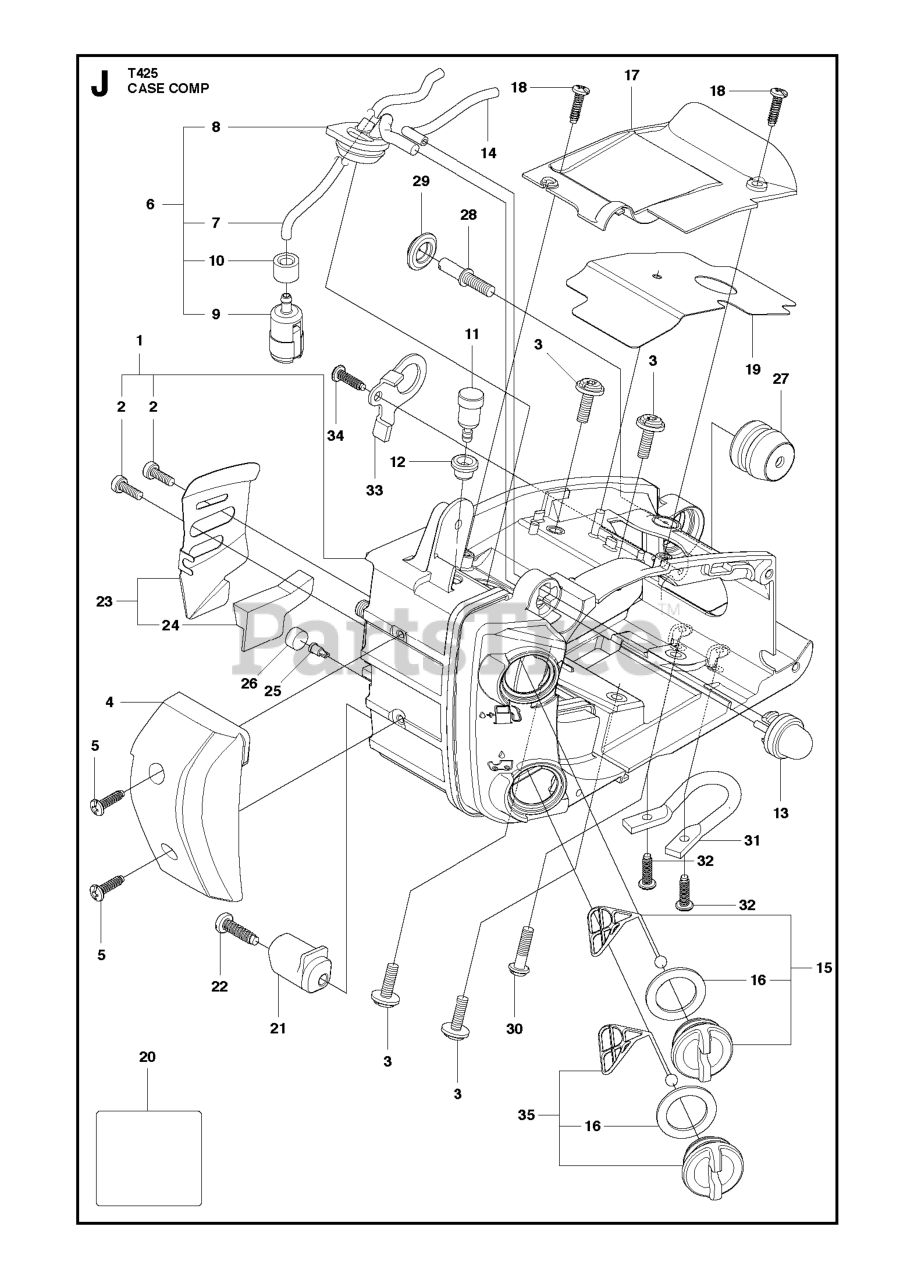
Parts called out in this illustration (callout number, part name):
9	FILTER
11	BREATHER
12	GROMMET
16	GASKET
28	BOLT
33	HANGER
